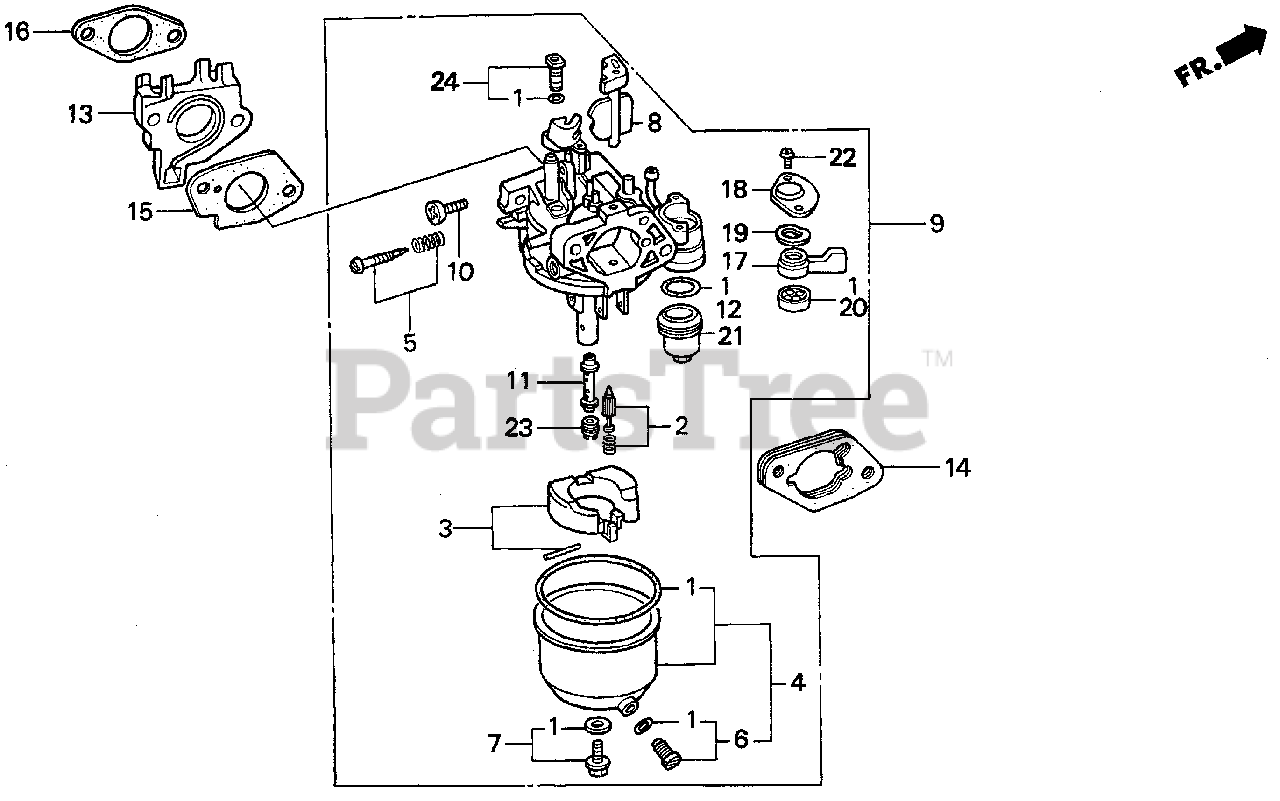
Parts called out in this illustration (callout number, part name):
1	GASKET SET
1	GASKET SET (INCLUDE 16173-001-004) (INCLUDES 16173-001-004)
2	VALVE SET, FLOAT
3	FLOAT SET
4	CHAMBER SET, FLOAT
5	SCREW SET, PILOT
6	SCREW SET, DRAIN (Honda Code 1672187). (CARBURETOR NO.)
7	SCREW SET B
8	CHOKE SET
9	CARBURETOR ASSY. (BE15B C)
9	CARBURETOR ASSY. (BE15B E)
10	SCREW, THROTTLE STOP
11	NOZZLE, MAIN
12	GASKET, FUEL STRAINER CUP
13	INSULATOR, CARBURETOR
14	SPACER, CARBURETOR
15	GASKET, CARBURETOR
16	GASKET, INSULATOR
17	LEVER, VALVE
18	PLATE, LEVER SETTING (CARBURETOR NO.)
19	SPRING, PETCOCK LEVER (CARBURETOR NO.)
20	GASKET, VALVE
21	CUP, FUEL STRAINER
22	SCREW, PAN (3X8)
22	SCREW, PAN (3X8) (CARBURETOR NO.)
23	JET, MAIN (#82)
23	JET, MAIN (#85)
23	JET, MAIN (#88) Use from Engine SN BE27A B to BE27A E.
24	JET SET, PILOT (#38)
